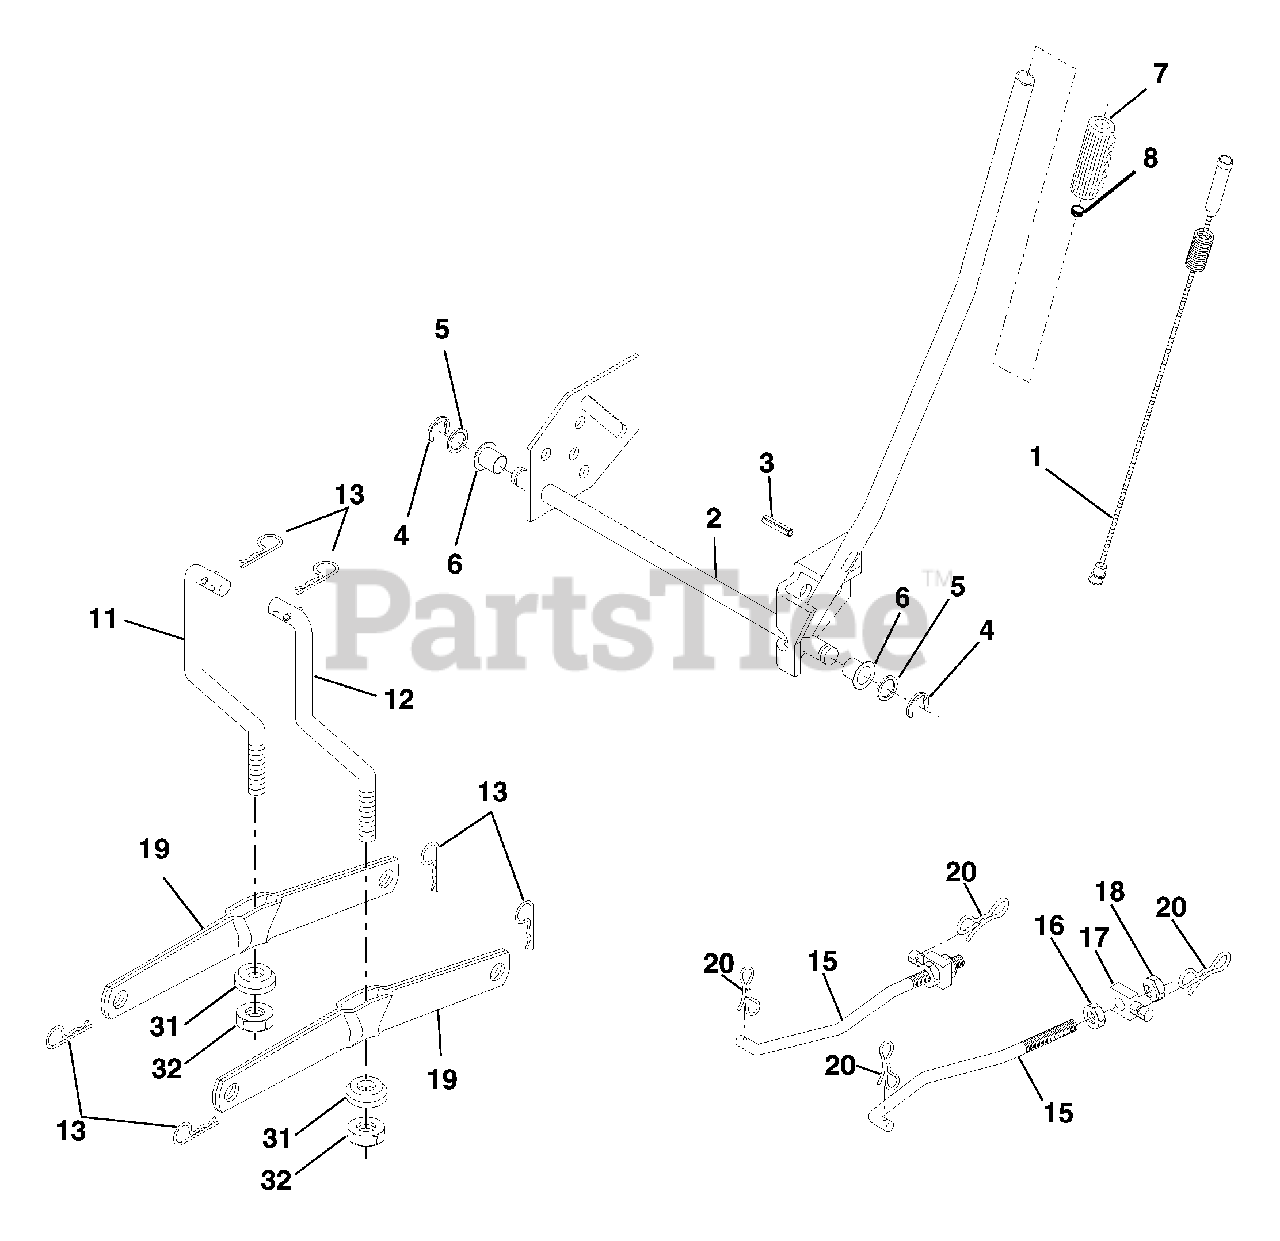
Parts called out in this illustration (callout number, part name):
1	Wire Asm Inner/Sprg W/plunger
2	Shaft Asm Lift RH w/Inf
3	Pin Groove 5/16 x 1.875
4	E Ring #5133-62
5	Washer 21/32 x 1 x 21 Ga.
6	Bearing Nylon Blk 629 Id
7	Grip Handle
8	Button Plunger
11	Link Lift LH Fixed Length
12	Link Lift RH Fixed Length
13	Retainer Spring
15	Link Front
16	Nut Jam Hex 1/2-13 unc
17	Trunnion
18	Nut Lock W/Wsh 1/2-13 unc
19	Arm Suspension Rear
20	Pin Cotter 7/16 Bow Tie Lock
31	Bearing Pvt Lift
32	Nut Crownlock 3/8 - 24
